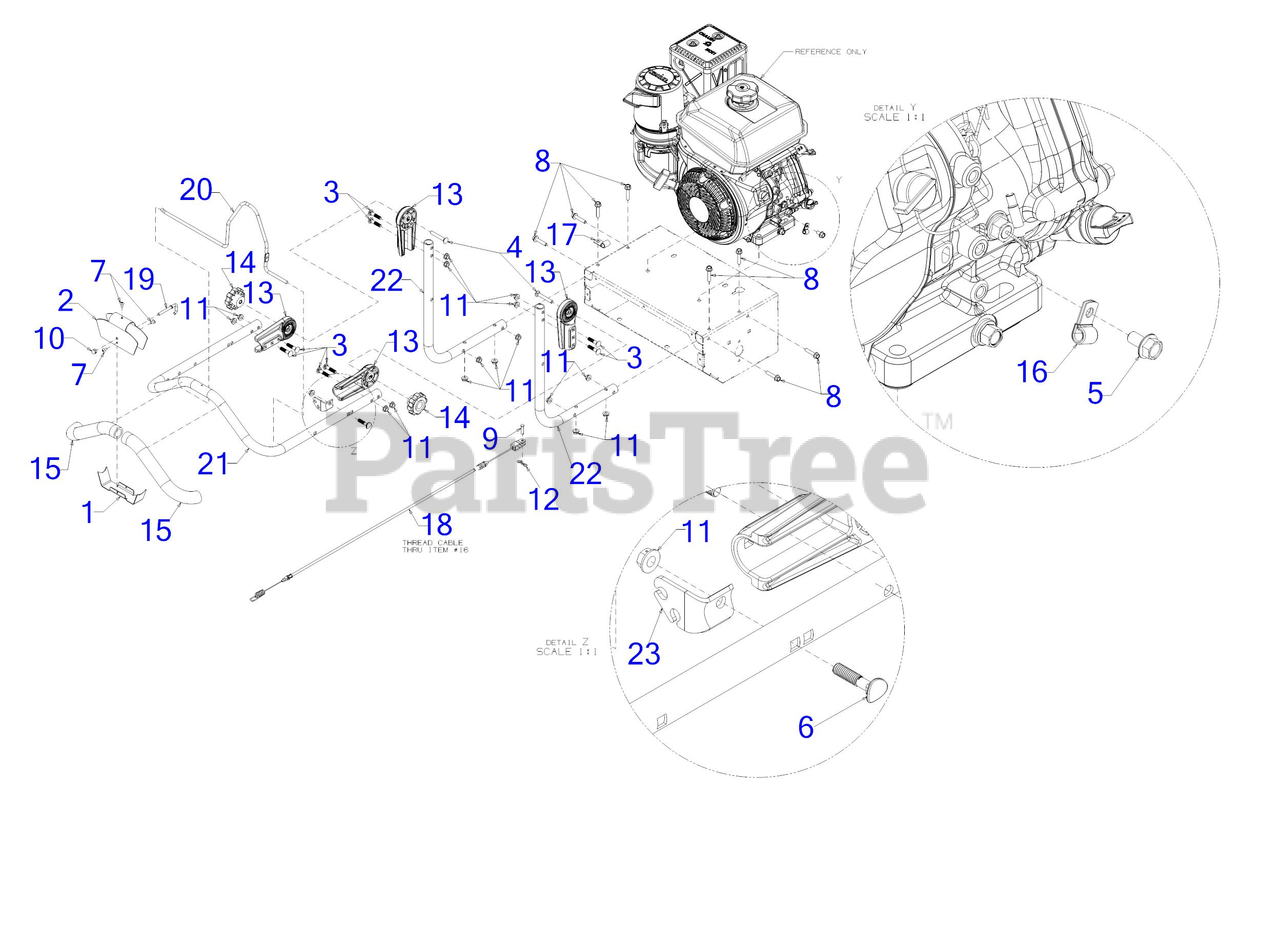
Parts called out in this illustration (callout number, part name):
1	SWITCH COVER BLOWER
3	CARRIAGE BOLT 5/16-18 x 1.50
4	SCRE W5/16-18 x 2.25 GR5
5	SCREW M8 x 1.25 x 16MM GR8.8
6	CARRIAGE BOLT 5/16-18 x 1.5
7	TORX SCREW #10-16 - .500
8	SCREW 5/16-18 x 1.50 GR5
9	CLEVIS PIN .25 x 1.00
11	FLANGE NUT
12	BOW TIE COTTER PIN 1/4-5/16
13	HANDLE ADJUST
14	KNOB-5/16-18
15	UPPER HANDLE GRIP
16	HOSE CLAMP
17	J TYPE CLIP
18	CABLE-BRAKE PUSH BLOWER
19	PARKING BRAKE HOOK ROD
20	BLOWER BRAKE BAIL
21	UPPER HANDLE TUBE
22	LOWER HANDLE TUBE
